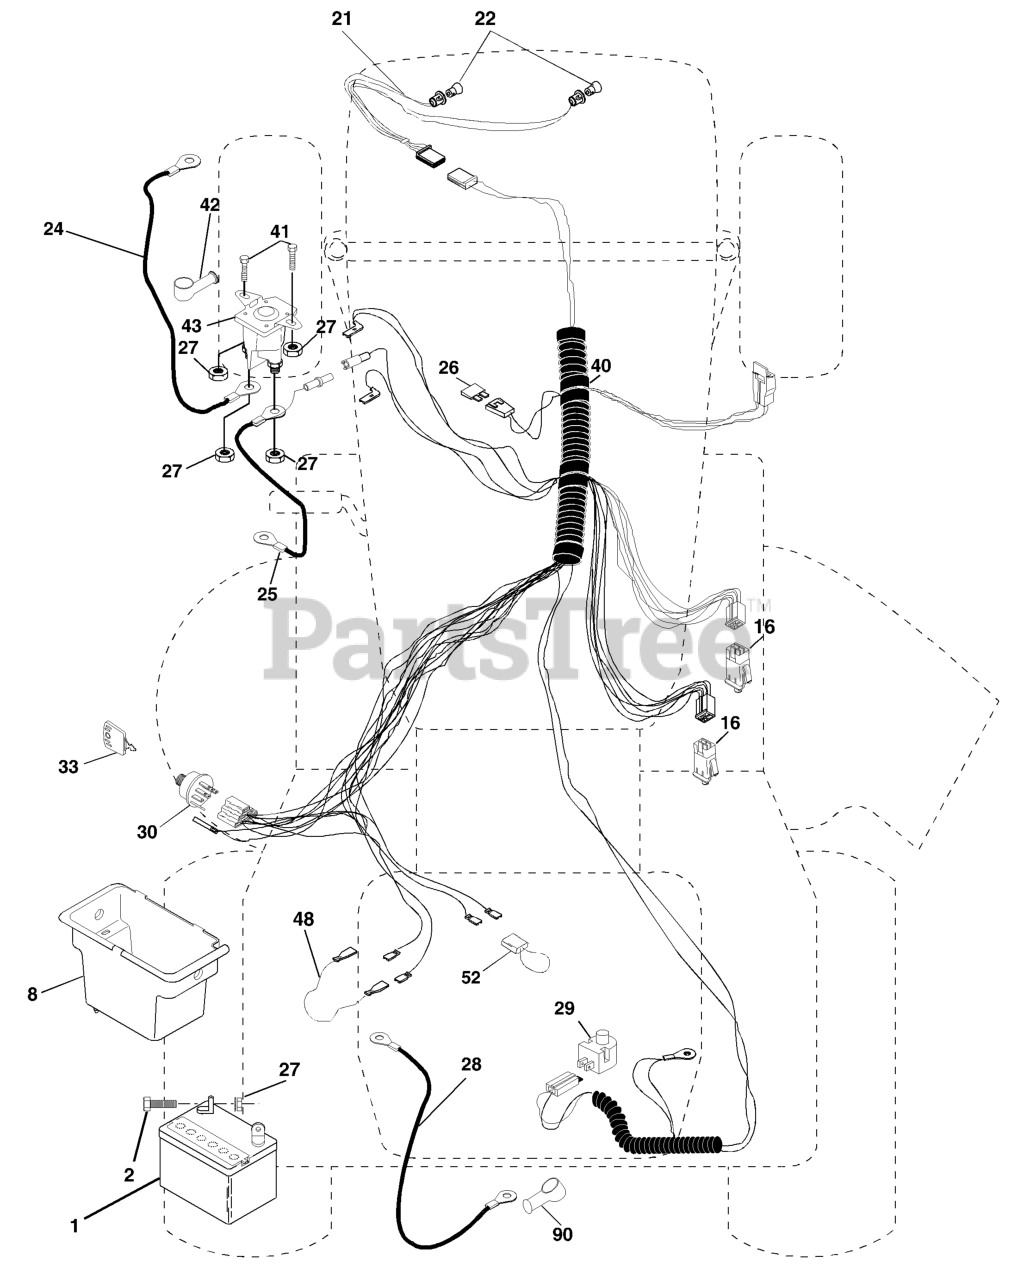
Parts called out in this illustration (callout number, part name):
1	Battery 12 Volt 25 Amp
2	BOLT.HEX.1/4.X.3/4.DICHROMATE
8	BOX.BATTERY.FENDER
16	SWITCH INTERLOOK PUSH-IN
24	BATTERY CABLE GT
25	CABLE BATTERY
26	FUSE 20AMP
27	NUT
28	CABLE T
29	RP.SWITCH.PLUNGER.NC.GRAY
30	IGNITION SWITCH
33	KEY MLD GEN DELTA
40	HARNESS.IGNITION
41	BOLT
42	TERMINAL COVER
43	SOLENOID
48	ADAPTER.AMMETER
52	WIRE PROTECTION LOOP
